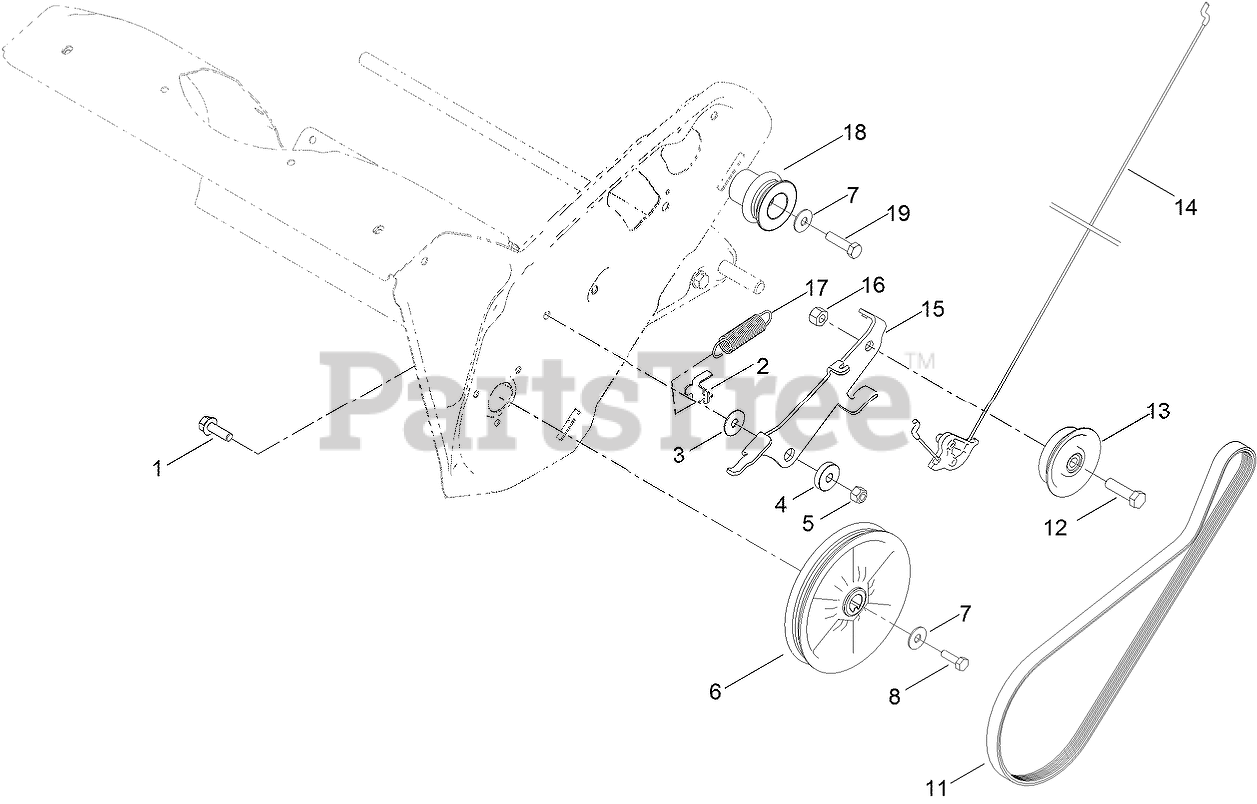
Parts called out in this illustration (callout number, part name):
1	SCREW-HHF
2	CLIP-SPRING
3	WASHER
4	BUSHING-PIVOT
5	NUT-LOCK, NI
6	PULLEY
7	WASHER-BELLEVILLE
8	SCREW-HH
11	BELT-DRIVE
12	SCREW-HH
13	PULLEY-IDLER
14	CABLE-CLUTCH
15	ARM-IDLER
16	NUT-LOCK, CONE
17	SPRING-EXTENSION
18	PULLEY-ENGINE
19	SCREW-HH
